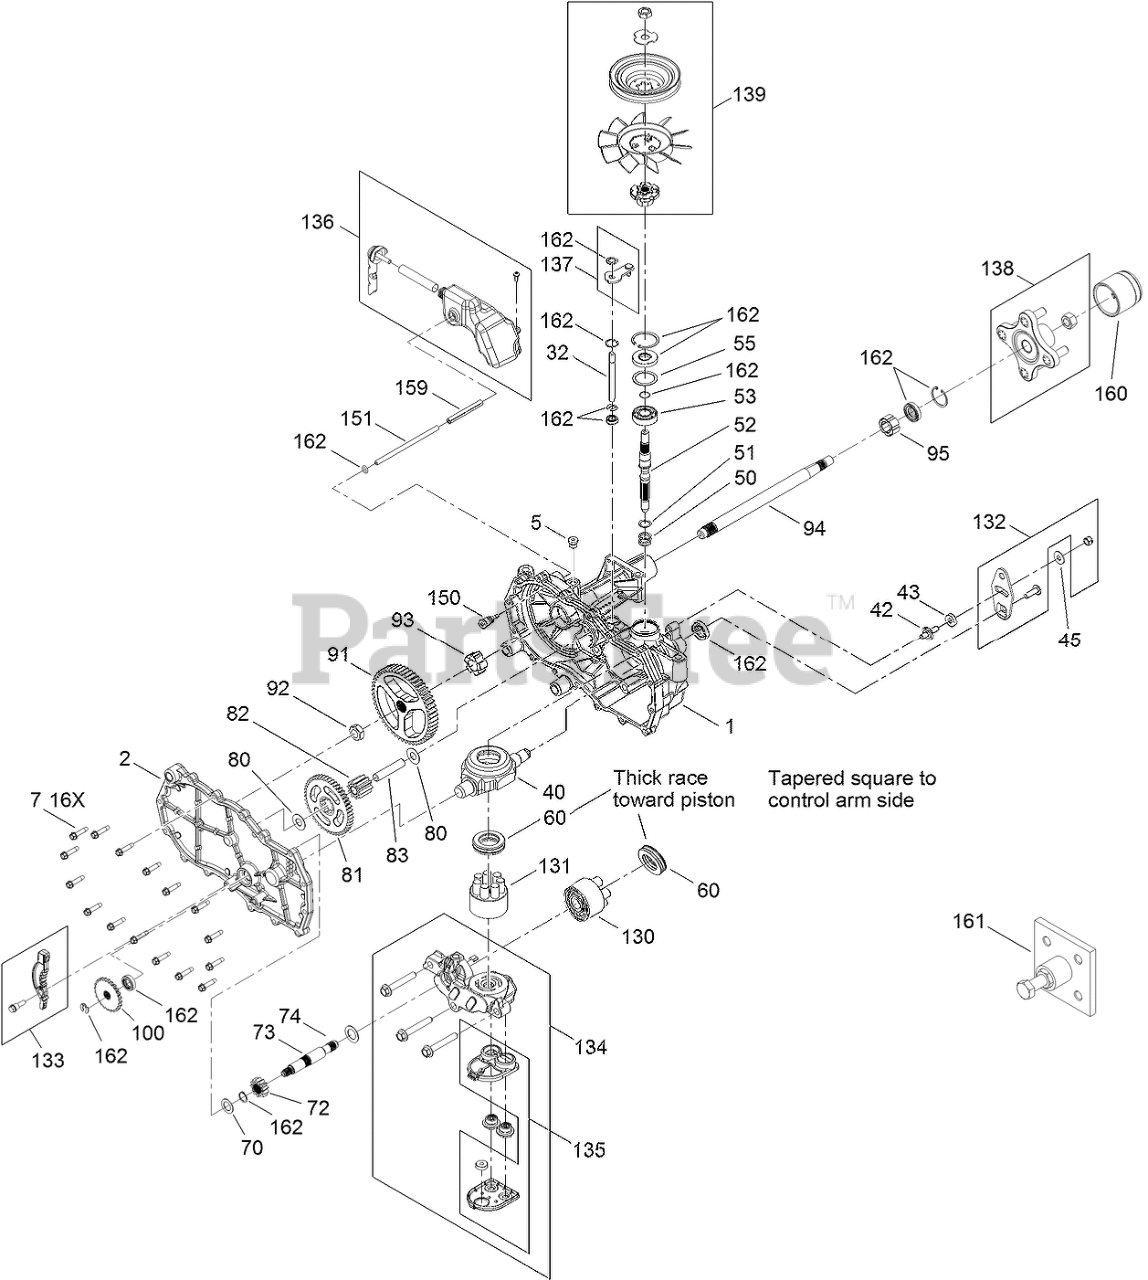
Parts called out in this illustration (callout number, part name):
1	MAIN HOUSING ASM
2	HOUSING SIDE KIT
5	PLUG-THREAD, STRAIGHT
7	SCREW-HHF
32	ROD-BYPASS
40	SWASHPLATE-TRUNNION
43	PUCK-FRICTION
45	WASHER
50	SPRING-COMPRESSION
51	WASHER
52	SHAFT-INPUT
53	BEARING-BALL
55	SPACER
60	BEARING-THRUST
70	WASHER-FLAT
72	GEAR-PINNION, 13T
73	SHAFT-MOTOR
74	WASHER
80	WASHER
81	GEAR-10T/48T
82	GEAR-JACKSHAFT, 10T
83	PIN-JACKSHAFT
91	GEAR-BULL
92	NUT-HJ
93	BUSHING-INBOARD
94	SHAFT-AXLE
95	BEARING-SLEEVE
100	DISC-BRAKE, COG
130	CYLINDER BLOCK KIT
131	PUMP BLOCK ASM
132	CONTROL ARM KIT
133	BRAKE ARM KIT
134	CENTER SECTION FILTER KIT
135	FILTER KIT
136	LH EXPANSION TANK KIT
137	BYPASS ARM KIT
138	HUB KIT
139	FAN PULLEY KIT
150	FITTING-SAE
159	CASE-TUBE
160	CAP-AXLE
161	PULLER-HUB, 4 BOLT
162	SEAL AND RING KIT
